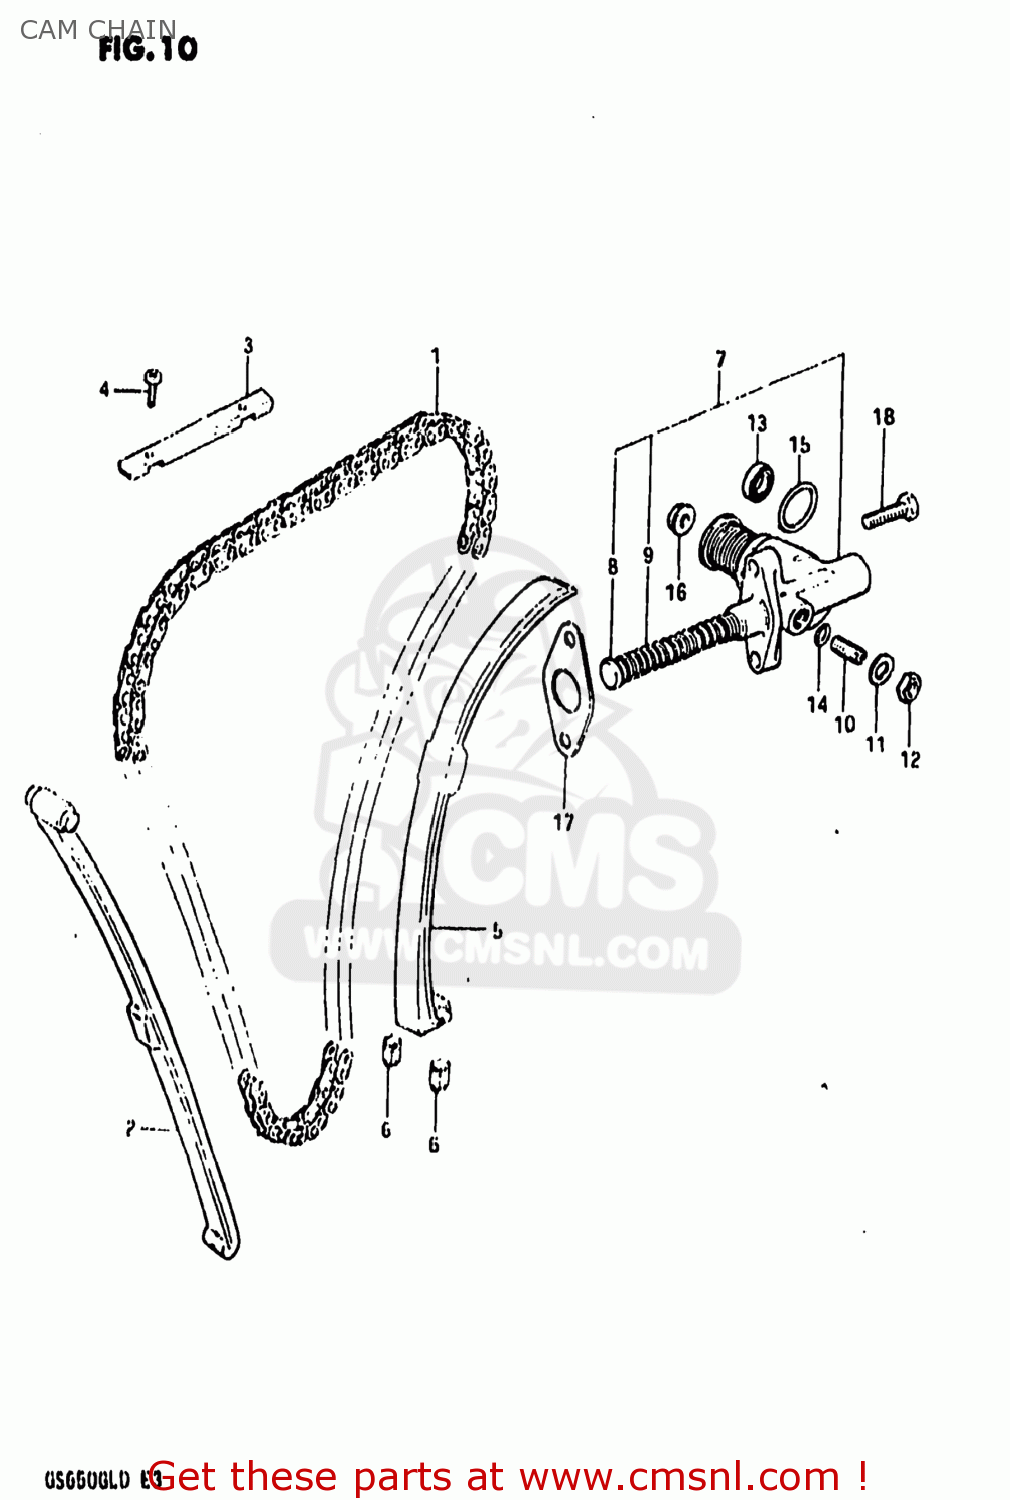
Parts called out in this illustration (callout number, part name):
1	CHAIN,CAMSHAFT DRIVE(120L)
2	GUIDE,CAM CHAIN
3	GUIDE,CAM CHAIN
4	SCREW
5	TENSIONER,CAM CHAIN
6	CUSHION,CAM CHAIN TENSIONER
7	ADJUSTER ASSEMBLY,TENSIONER
8	ROD,PUSH
9	SPRING
10	SCREW,TENSIONER ADJUST
11	WASHER,8.5X16X
12	NUT
13	OIL SEAL
14	O-RING
15	O-RING
16	NUT
17	GASKET,TENSIONER ADJUSTER (MCA)
18	SCREW
